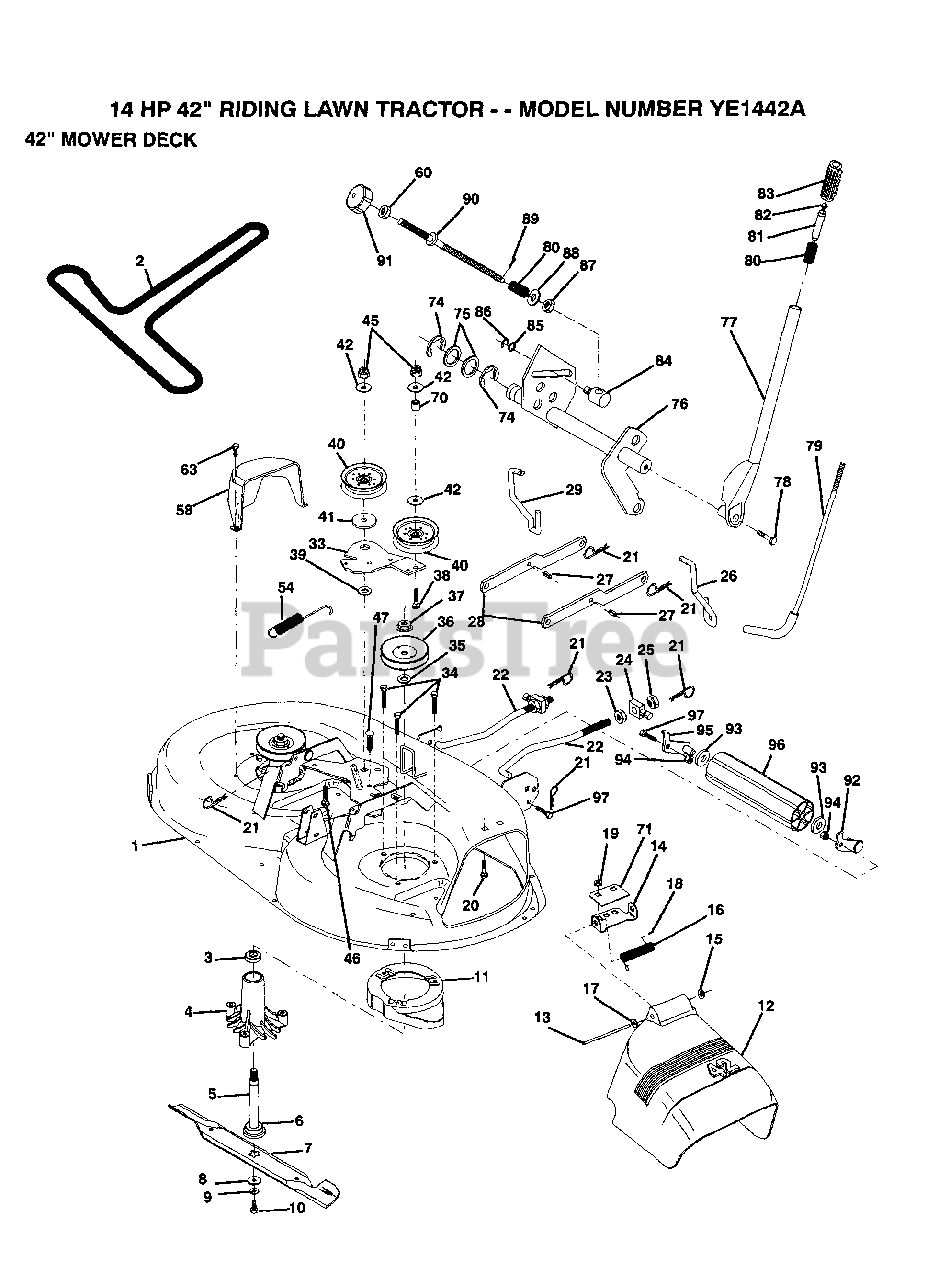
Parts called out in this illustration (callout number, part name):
2	BELT-V.92.4.MWR
3	BEARING
4	HSG ASM MANDREL
6	BEARING.BALL
8	WASHER BLADE
10	BLADE BOLT
12	DEFLECTOR.SHIELD
13	HINGE ROD
14	DEFLECTOR BRKT
15	NUT PUSH M
16	SPRING TORSION
17	WASHER
18	CAP-SLEEVE LT
20	BOLT
22	LINK.FRONT
23	NUT
24	TRUNION
25	NUT.LK.W/WSH.1/2.
26	LIFT LINK RH
27	"PIN,SPRING"
28	SUSP ARM ASM REAR
29	LINK LIFT LH
33	IDLER ARM
35	WASHER
38	BOLT
39	HARDENED WASHER
40	FLAT IDLER PULLEY
41	SPACER RETAINER
42	WASHER
46	BOLT
47	XMAS TREE FASTNER
54	SPRING.EXTENSION
57	CLUTCH ROD SECOND
60	NUT
63	SCREW LT
71	STIFFENER BRKT
75	WASHER
76	LIFT SHAFT ASM
78	"BOLT,HEX"
79	LEVER ROD LT
80	SPRING T
83	GRIP
84	TRUNION LT
85	WASHER
86	KLIP RING
87	NUT T
88	WASHER
90	ROD LIFT LT
93	WASHER
97	BOLT
